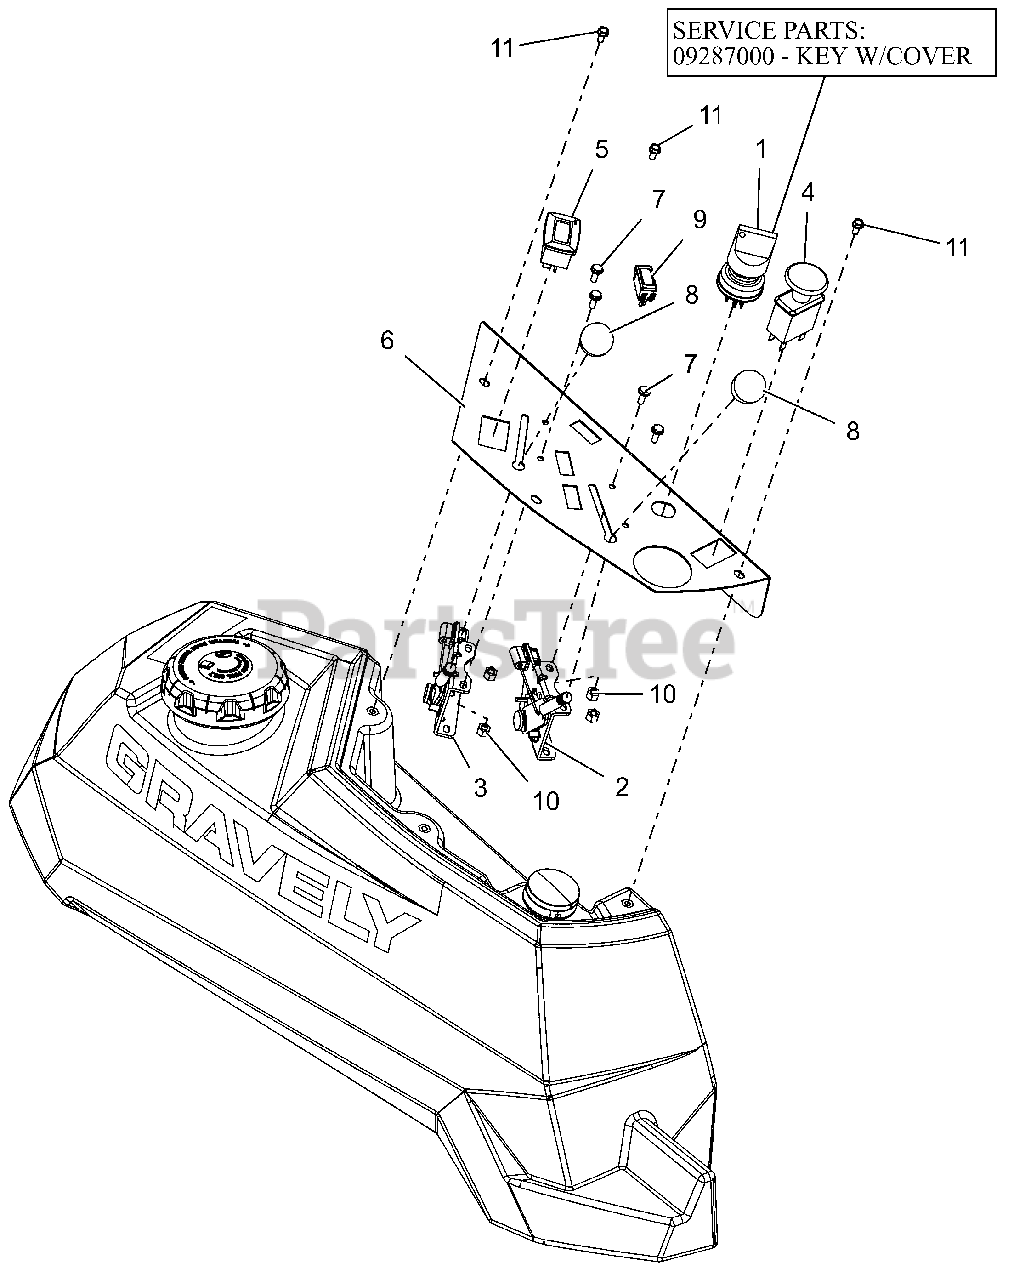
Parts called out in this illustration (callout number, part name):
1	SWITCH, IGNITION
1	KEY, W/ SHIELD
2	CABLE, PRO-CONTROL 28.50
3	CABLE, PRO-CONTROL 31.50"
4	SWITCH, CLUTCH
5	METER, HOUR W/MAINTENANCE
6	PT100 CONTROL PANEL - RED
7	@SCR-MCH 10-24X.50 HWH YWZC
8	KNOB-CONTROL-BLACK .38-16X.50
9	LIGHT,INDICATOR
10	@NUT-LK-NYL 10-24 W/INSRT YWZC
11	SCR-MCH 10-24X.38 HWHSTAINLESS
